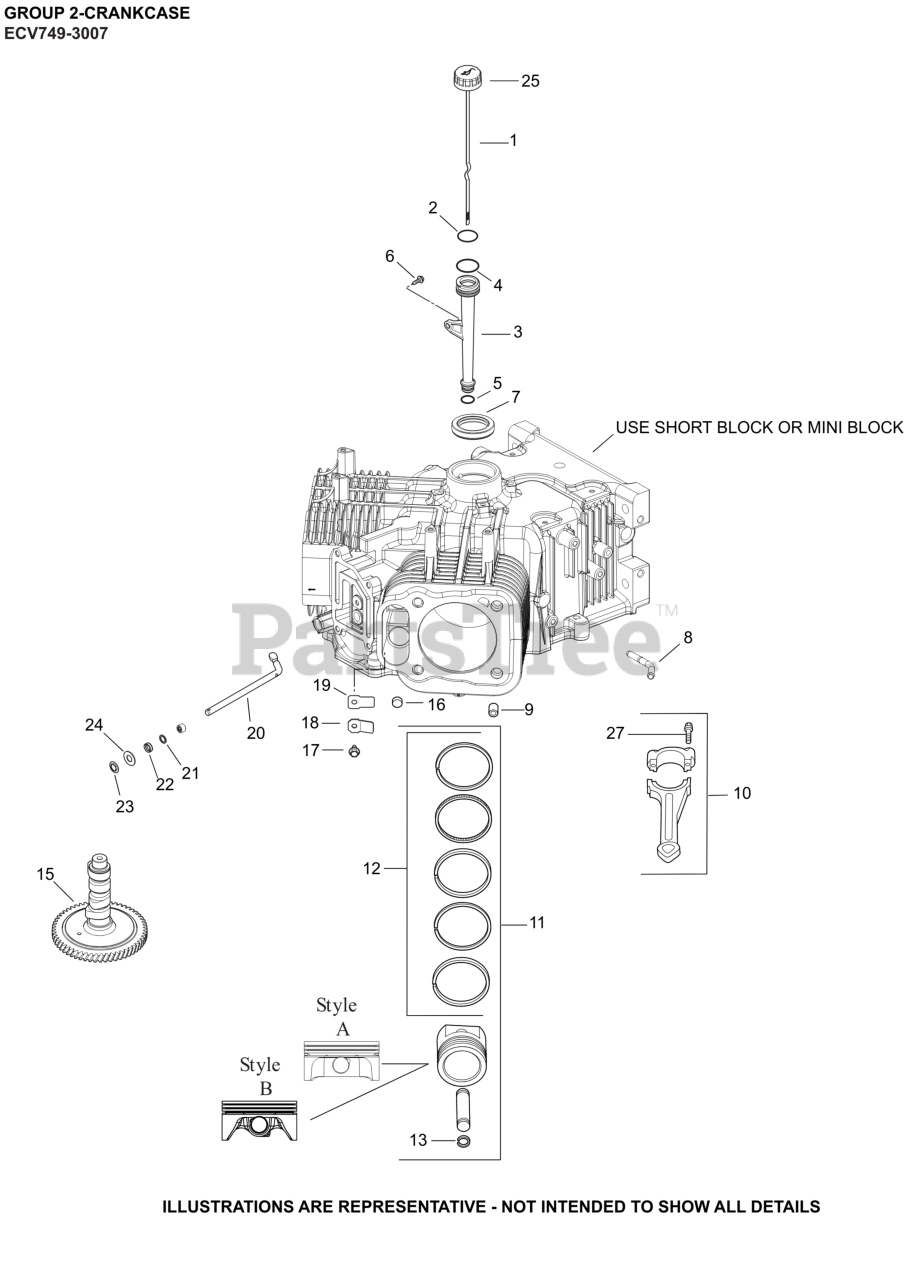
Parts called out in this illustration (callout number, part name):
1	DIPSTICK, ASSY
2	O-RING, DIPSTICK
3	TUBE ASSEMBLY
4	O-RING, UPPER OIL FILL TUBE
5	O-RING, LOWER OIL FILL TUBE
6	SCREW, FLG THD FRM M5X0.8X13
7	SEAL, OIL (HELIX LIP)
9	PIN, LOCATING
10	ROD, ASSEMBLY CONNECTING
11	KIT, PINNED PSTN/RING SET (STD)
11	KIT, PINNED PSTN/RING SET (.08)
11	KIT, PINNED PSTN/RING SET (.25)
11	KIT,PSTN/RING SET (.50)-USE 25 874 20-S
12	RING, SET (STD) PINNED
12	RING, SET (.08) PINNED
12	RING, SET (.25) PINNED
12	RING, SET (.50) PINNED
13	RETAINER, PISTON PIN
15	KIT, CAMSHAFT
16	PLUG, CUP
17	SCREW, FLG THD FRM M5X.8X10
18	RETAINER, BREATHER REED
19	REED, BREATHER
20	SHAFT, GOVERNOR CROSS
21	WASHER, FLAT 11/32"
22	SEAL, GOVERNOR CROSS SHAFT
23	RETAINER, RING
24	WASHER, FLAT 9 MM
25	KIT, OIL FILL CAP (YELLOW)
27	KIT, ROD BOLTS-(#25086677S)
